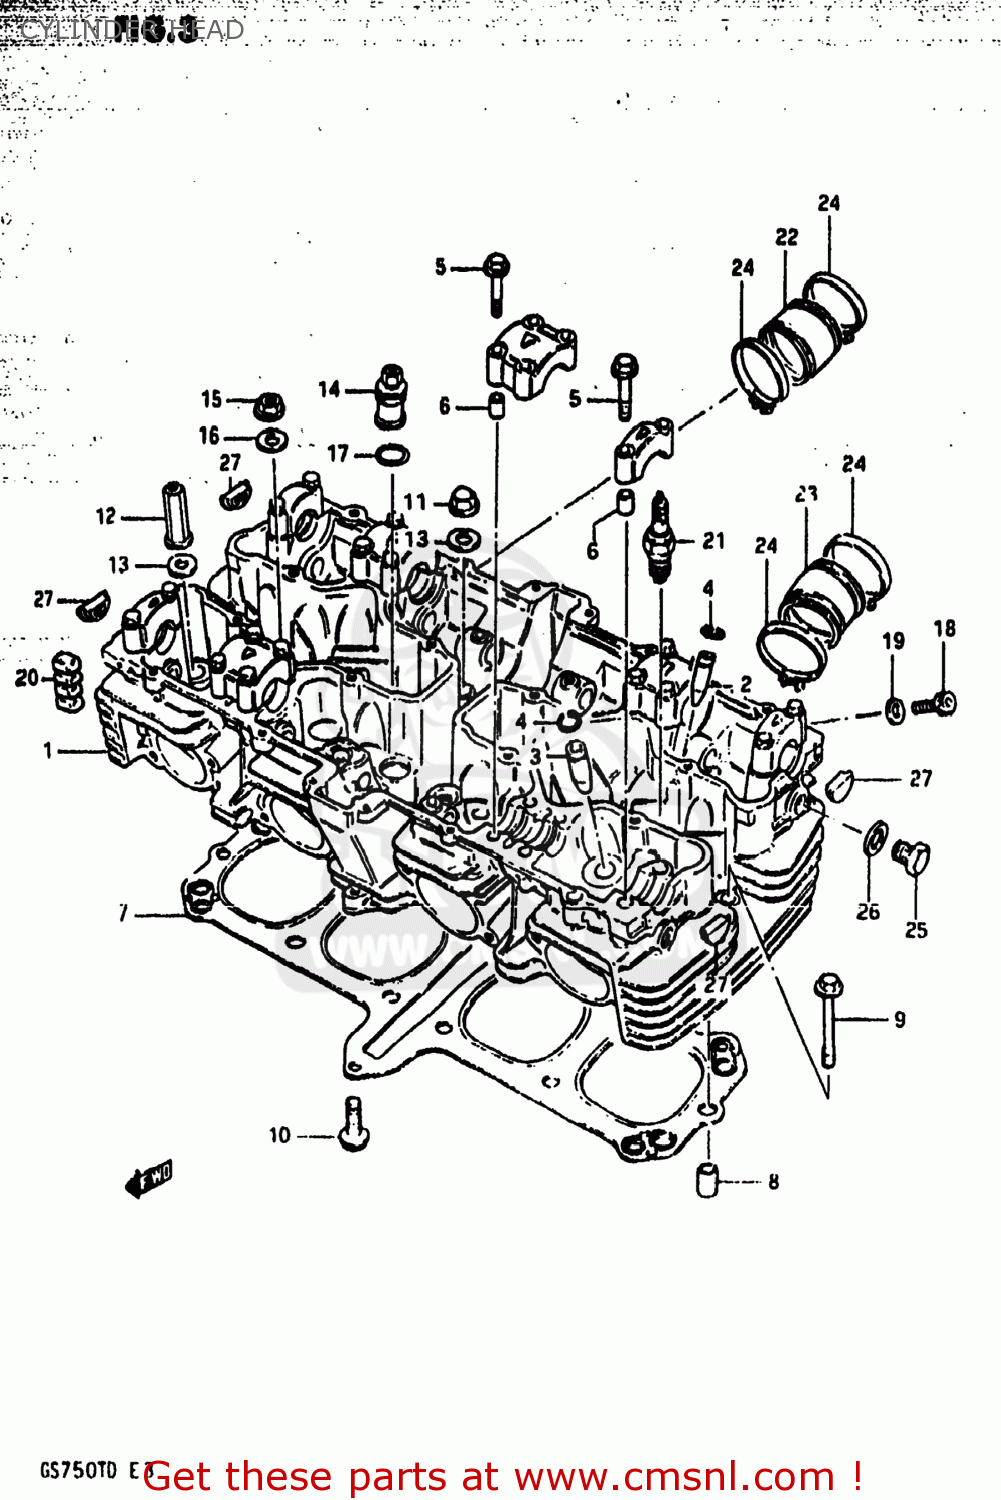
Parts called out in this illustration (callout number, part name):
1	HEAD ASSEMBLY,CYLINDER
2	GUIDE,INTAKE VALVE
3	GUIDE,INTAKE VALVE
4	RING,SNAP
5	BOLT(6X39)
6	PIN(6.2X8X11)
7	GASKET,CYLINDER HEAD (MCA)
8	PIN
9	BOLT
10	BOLT
11	NUT
12	NUT
13	GASKET(10.5X22X2) (NAS)
14	NUT,CYLINDER HEAD SEAL
15	NUT
16	WASHER(10.5X22X2.3)
17	O RING(D:2.4,ID:16.8)
18	BOLT
19	GASKET(5.3X9.3X1.2) (NAS)
20	PAD,CYLINDER
21	SPARK PLUG D8EA
22	PIPE,INTAKE,R
23	PIPE,INTAKE
24	CLAMP
25	PLUG
26	GASKET(14X19.2X2) (NAS)
27	PLUG
